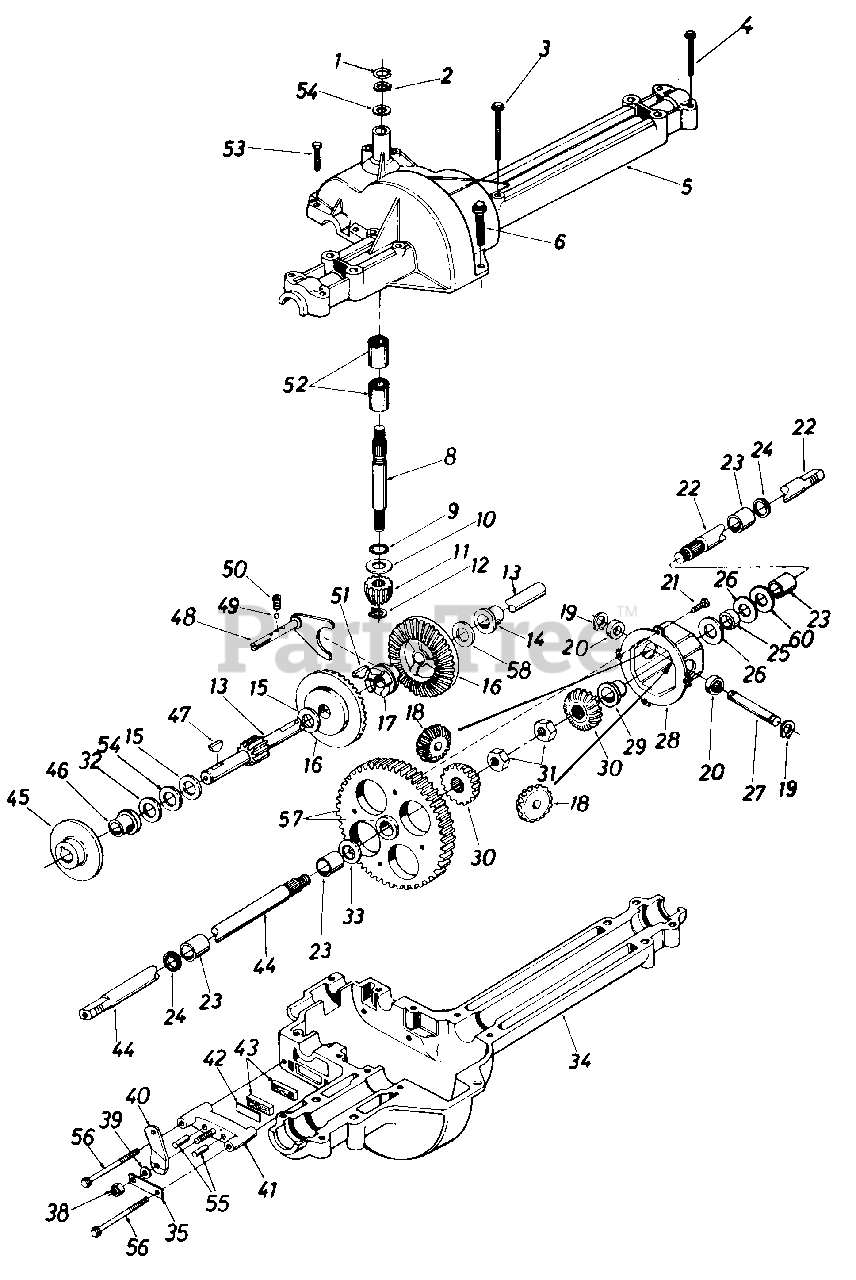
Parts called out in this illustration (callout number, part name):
1	Wire Ring
2	Retaining-Ring
3	Hex Bolt 1/4-20 x 1.75" Lg.
4	Hex Tap Scr. 1/4-20 x 1.25" Lg.
5	Upper Housing
6	Hex TT-Tap Scr. 1/4-20 x .75" Lg.
8	Input Shaft
9	Square Seal 5/8" I.D.
10	Thrust Washer 5/8" I.D. x 1.25" O.D.
11	Pinion Input 14T
12	Retaining Ring
13	Drive Shaft
14	Flange Brg. 5/8" I.D. x 3/4" Lg.*
15	Fl-Wash. 5/8" I.D. x 1.25"
16	Bevel Gear 42T
17	Clutch Collar
18	Miter Gear 15T (H.D.)
19	Snap Ring
20	Thrust Bearing
21	Pan Head Scr. 1/4-20 x .50" Lg. w/Patch
22	Axle R.H. Ass'y.
23	Sleeve Bearing 3/4" I.D. x 1.0" Lg.
24	Oil Seal 3/4" I.D.
25	Axle Spacer
26	Fl-Wash. .760" I.D. x 1.5" O.D.
27	Cross Shaft
28	Differential Cam Ass'y.
30	Miter Gear
31	Hex Jam Nut 1/2-20 Thd.
32	Washer
33	Fl-Wash. .760" I.D. x 1.5" O.D.
34	Lower Housing
35	Anti-Rotation Brkt.
38	Hex Nut 5/16-24 Thd.
39	Fl-Wash. .344" I.D. x .875" O.D.
40	Actuating Arm
41	Brake Yoke
42	Puck Plate
43	Brake Puck
44	Axle L.H. Ass'y.
45	Brake Disc
46	Flange Bearing 5/8" I.D. x 15/16" Lg.
47	Woodruff Key 3/16 x 5/8 HT
48	Shift Fork Ass'y.
49	Ball Detent .250" Dia.
50	Spring Detent
51	#9 Hi-Pro Key 3/16" x 3/4" Dia. HT
52	Needle Brg. 5/8" I.D. x 1/2" Lg.
53	Hex Bolt 1/4-20 x 1.00" Lg.
54	Fl-Wash. 5/8" I.D. x 1" O.D. x .020 Thk.
55	Actuating Pin 5/16" Dia.
56	Hex Wash Hd. Self-Tap Scr. 1/4-20 Thd.
57	Differential Gear 72T Ass'y. w/ Bearing
58	Fl-Wash. 5/8" I.D. x 1" O.D. x .020 Thk.
60	Washer
